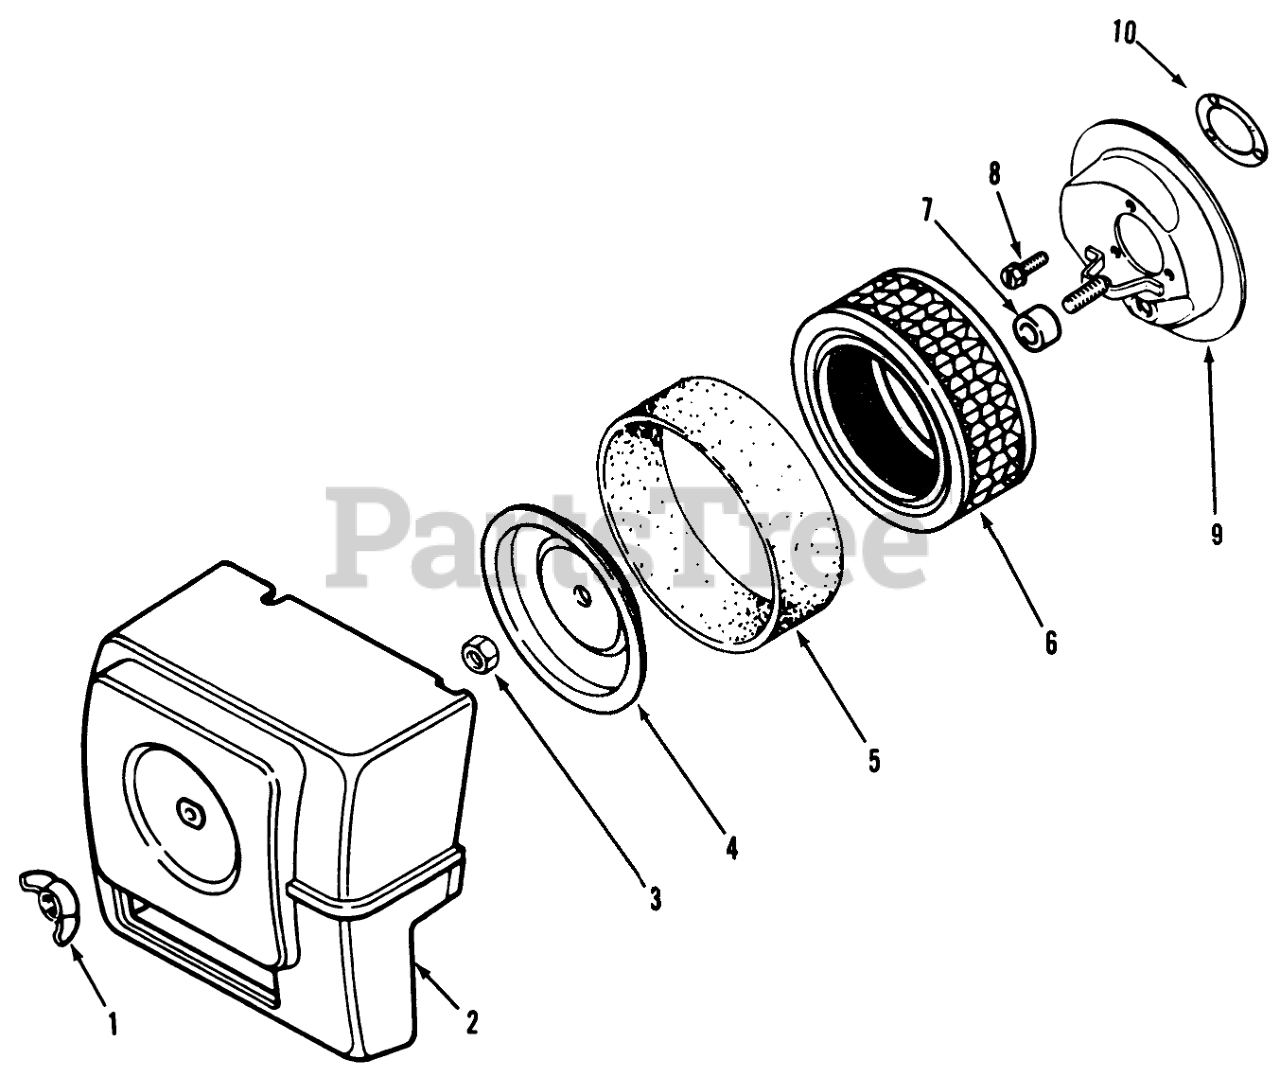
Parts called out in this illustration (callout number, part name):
1	Nut-Wing
2	Cover
4	Air Cleaner Element Cover
5	Element-Precleaner
6	Element
8	Screw
9	Base-AirCleaner
10	Gasket
